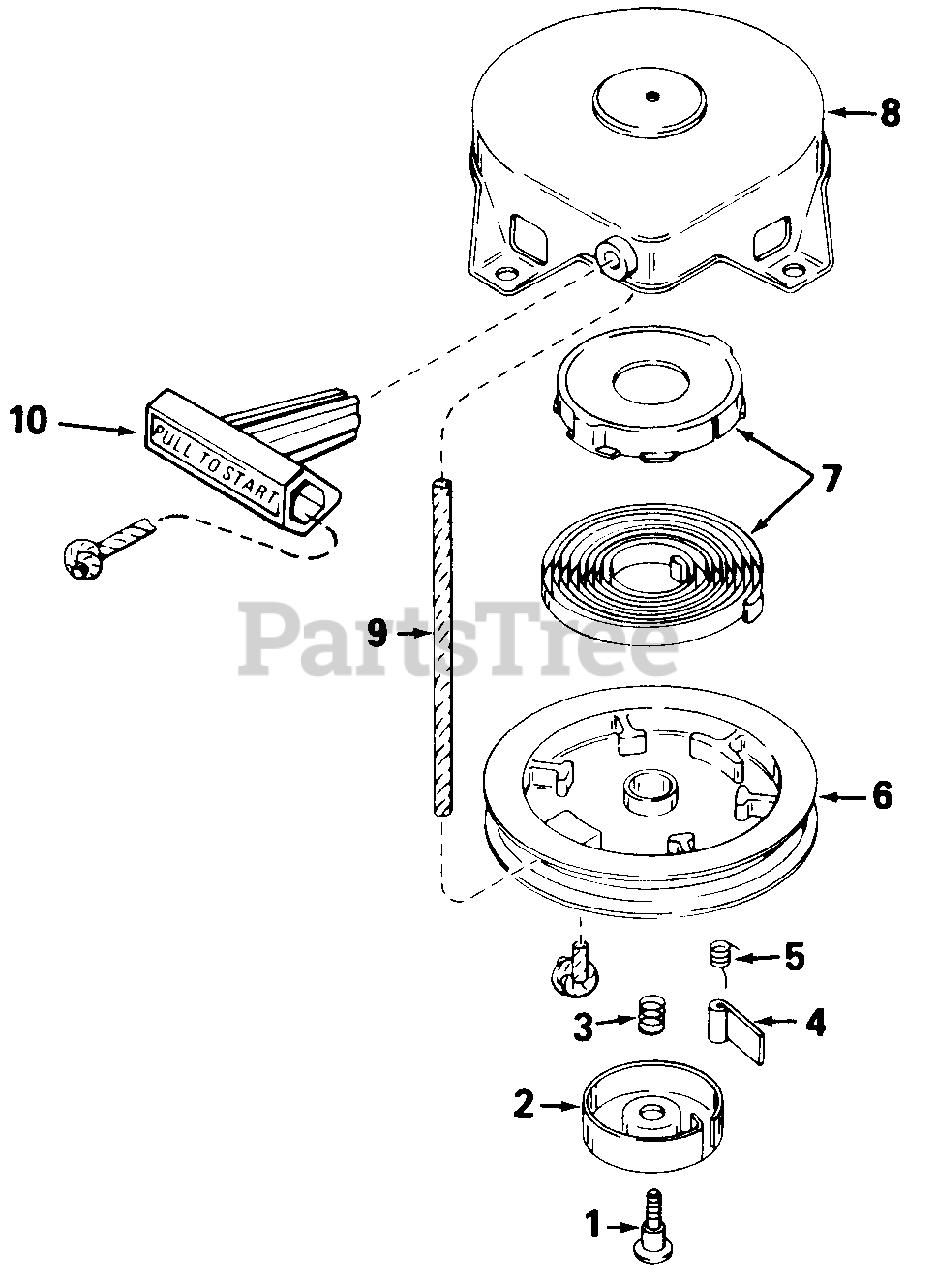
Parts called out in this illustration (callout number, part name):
1	Screw, Retainer
2	Retainer, R.H.
3	Spring,Brake
4	Dog, Starter
5	Spring, R.H. Dog
7	Spring & Keeper Ass'y.
8	Housing Ass'y., Starter
9	Rope, Starter
10	Handle Ass'y., Starter
